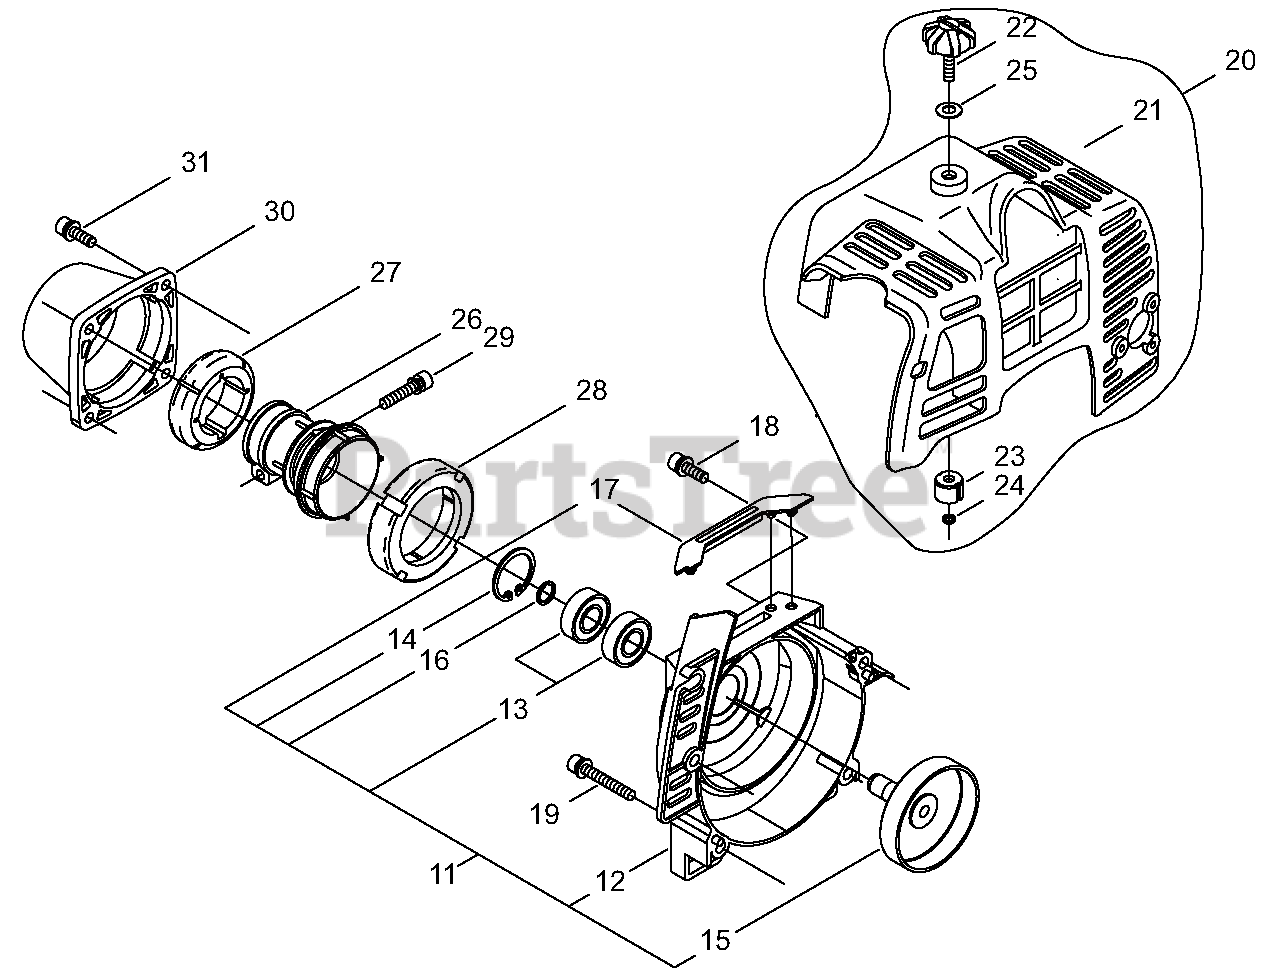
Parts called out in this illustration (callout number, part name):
11	SHORT BLOCK
12	CASE, FAN
13	BEARING, BALL - 6000ZZ
14	RING, RETAINING - 26
15	DRUM, CLUTCH
16	RING, RETAINING
17	CUSHION
18	SCREW - 5X16
19	SCREW - 5X45
20	ENGINE COVER ASSY
21	COVER, ENGINE
22	THUMBSCREW
23	INSULATOR
25	WASHER - CONICAL
26	CLAMP, MAIN PIPE
27	CUSHION - FRONT
28	CUSHION - REAR
29	SCREW - 5X25
31	SCREW - 5X16
